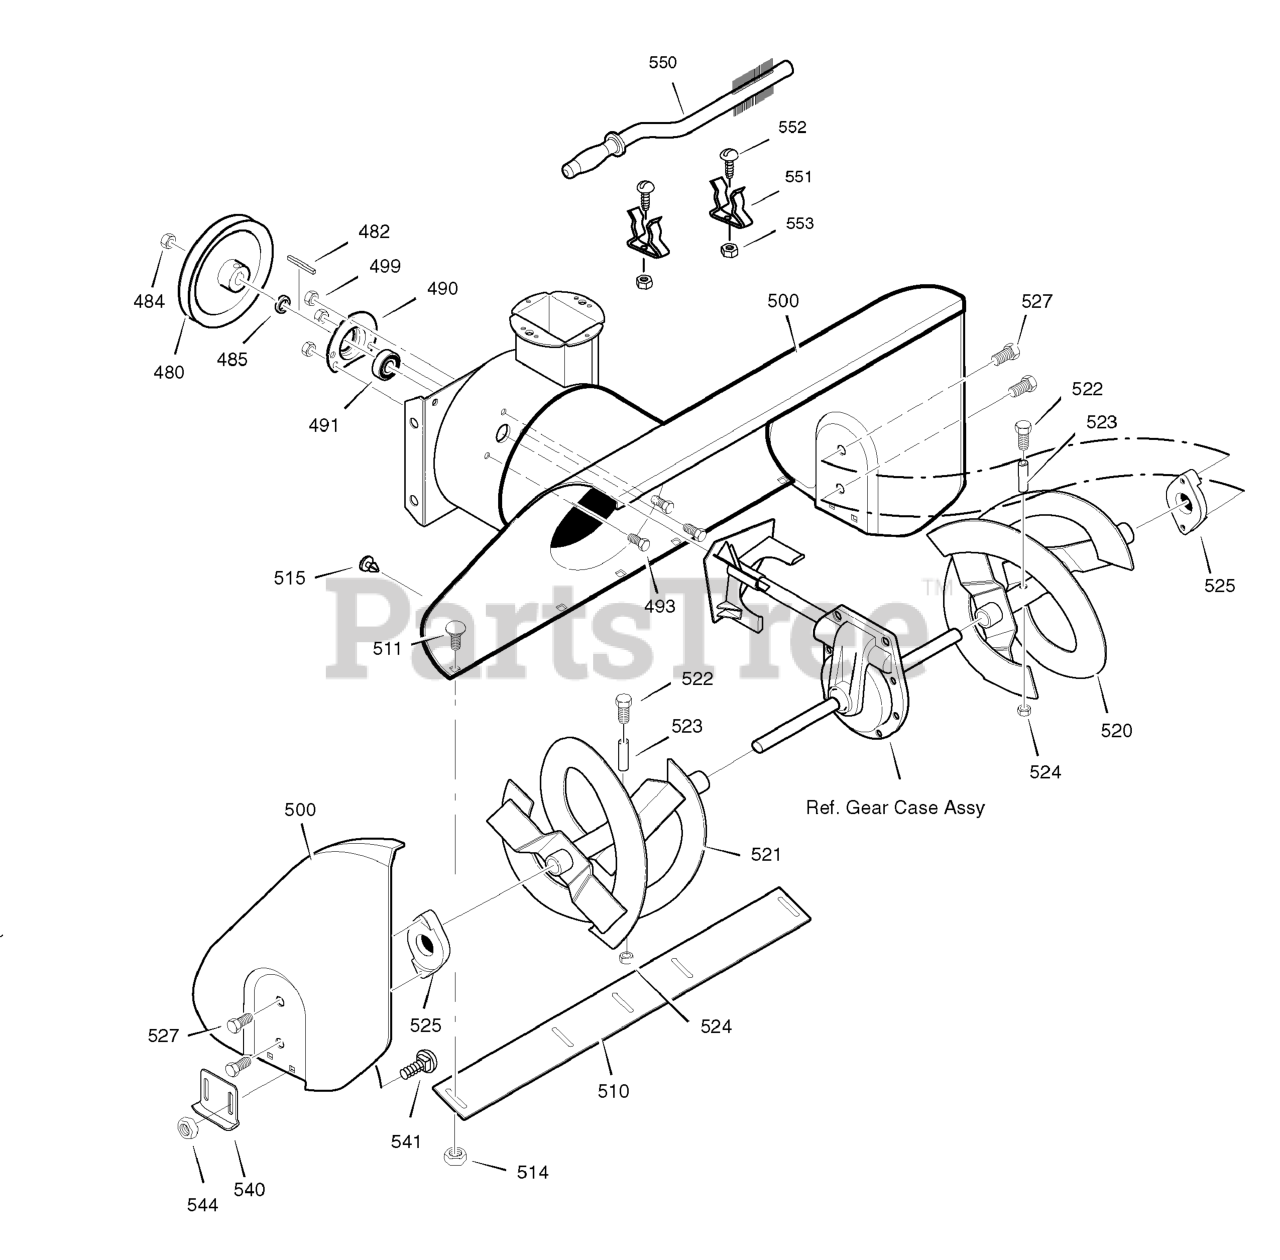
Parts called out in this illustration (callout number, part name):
480	PULLEY, 4L 8.40 OD.
482	KEY, SQUARE 3/16 X 3/4
484	NUT, .50-20 HEXWDFLLK
485	SPACER, FRICTION PULLEY
490	RETAINER, BALL BEARING
491	BEARING, BALL
493	BOLT, HEX 5/16-18 X .62
499	NUT, 5/16-18 HEXWDFLLK
500	HOUSING, ASSEMBLY
510	BLADE, SCRAPER
511	BOLT, 1/4-18 X .75
514	NUT, 5/16- 18
515	PLUG, PANEL
520	AUGER, ASSEMBLY, LH
521	AUGER, ASSEMBLY, RH
522	SCREW, 1/4-20 X 1.75
523	SPACER, SLEEVE
524	NUT, 1/4-20
525	BEARING, FLANGE
527	SCREW, 5/16-18 x 0.75
540	SKID, HEIGHT ADJUST
541	BOLT, 5/16-18 X .75
544	NUT, 5/16- 18
550	BRUSH, CLEANOUT
551	CLAMP, SPRING
552	SCREW
553	NUT
